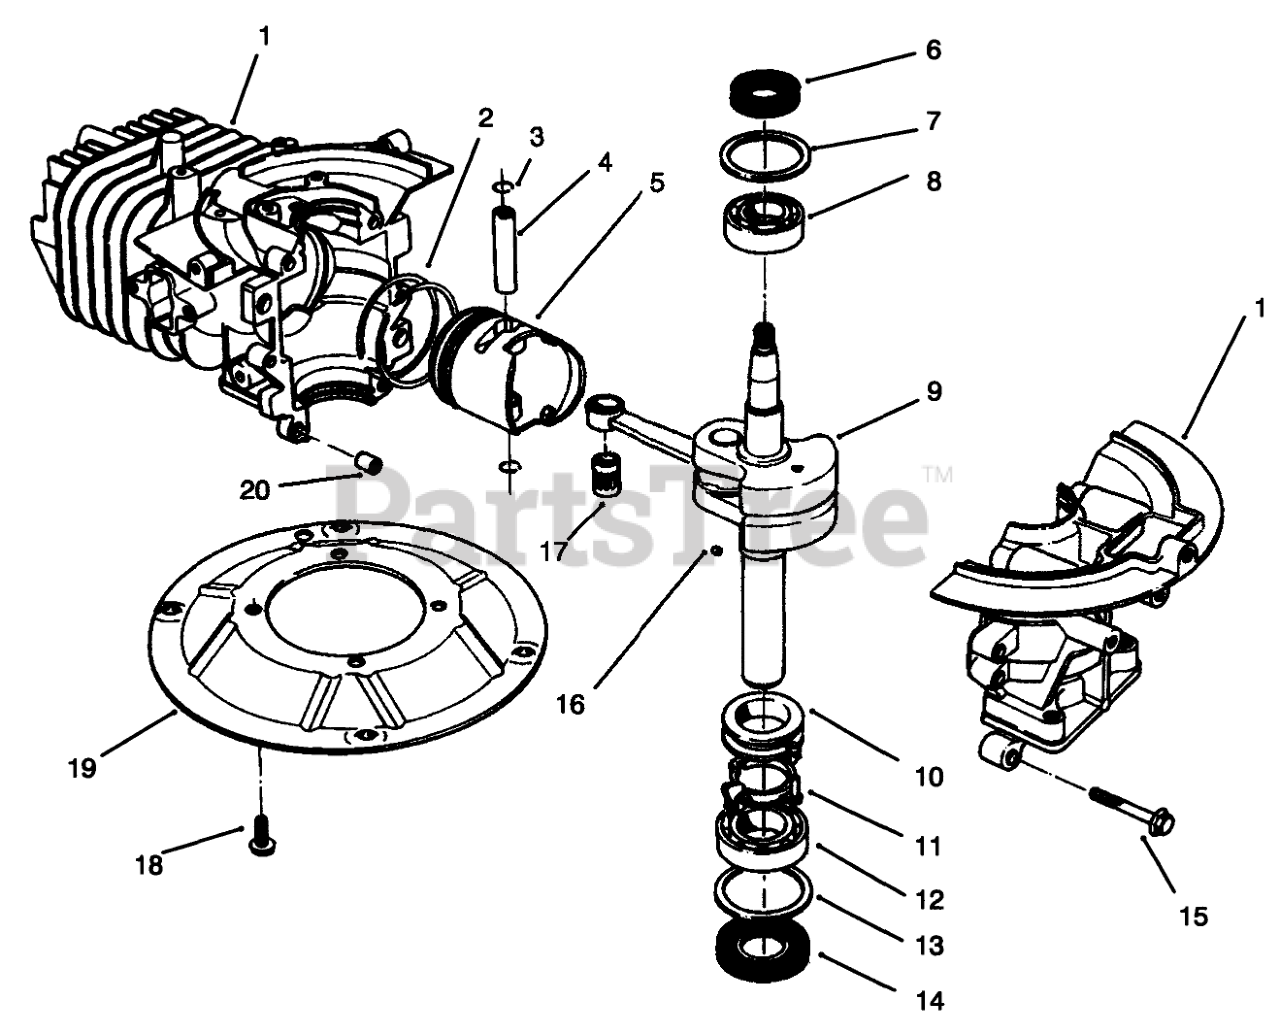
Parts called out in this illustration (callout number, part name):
1	CRANKCASE
2	RING SET
4	Pin-Wrist
5	PISTON
6	OIL SEAL
7	WASHER-UPPER
8	BEARING-UPPER
9	CRANKSHAFT
10	SPACER
11	BRACKET
12	LOWER BRG
13	WASHER-LOWER
14	SEAL-OIL
17	BEARING
19	PLATE-MOUNTING
